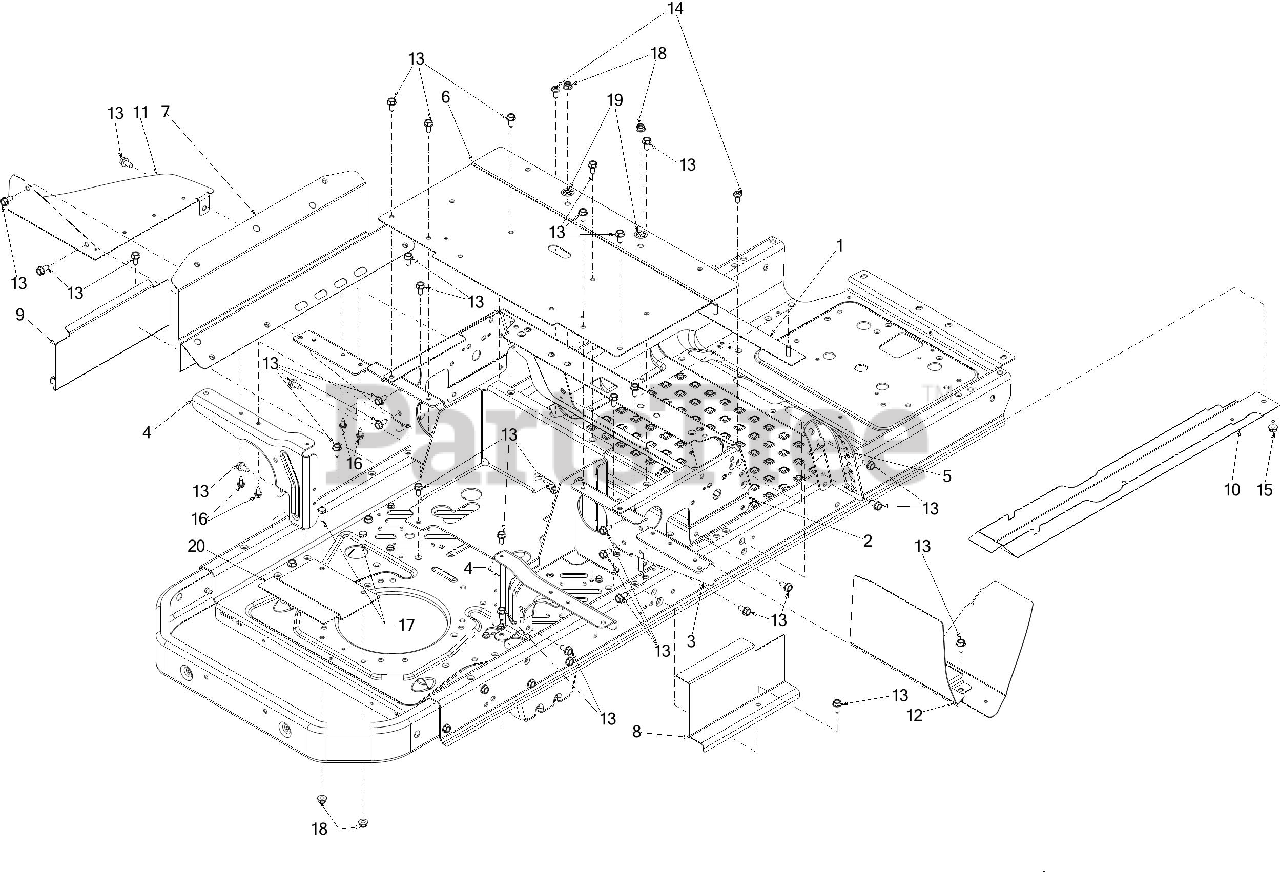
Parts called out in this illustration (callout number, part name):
1	SEAT PIVOT MOUNTING BRACKET
3	REAR SEATBOX BRACE
4	REAR TANK BRACKET
5	HEIGHT INDEX BRACKET
6	SEATBOX TOP PLATE
7	CONTROL PANEL PLATE
8	SIDE SHIELD (RH)
9	SIDE SHIELD (LH)
10	HARNESS SHIELD
11	CONTROLLER SHIELD
12	CONSOLE SHIELD (RH)
13	SCREW 5/16-18 x .750
14	SCREW 5/16-18 x .750
15	SCREW 5/16-18 x .500
16	SCREW 1/4-20X.625
17	SCREW 5/16-18 x .75 GR5
18	FLANGE LOCK NUT 5/16-18
19	PUSH NUT 5/16
20	SUPPORT BRACKET
